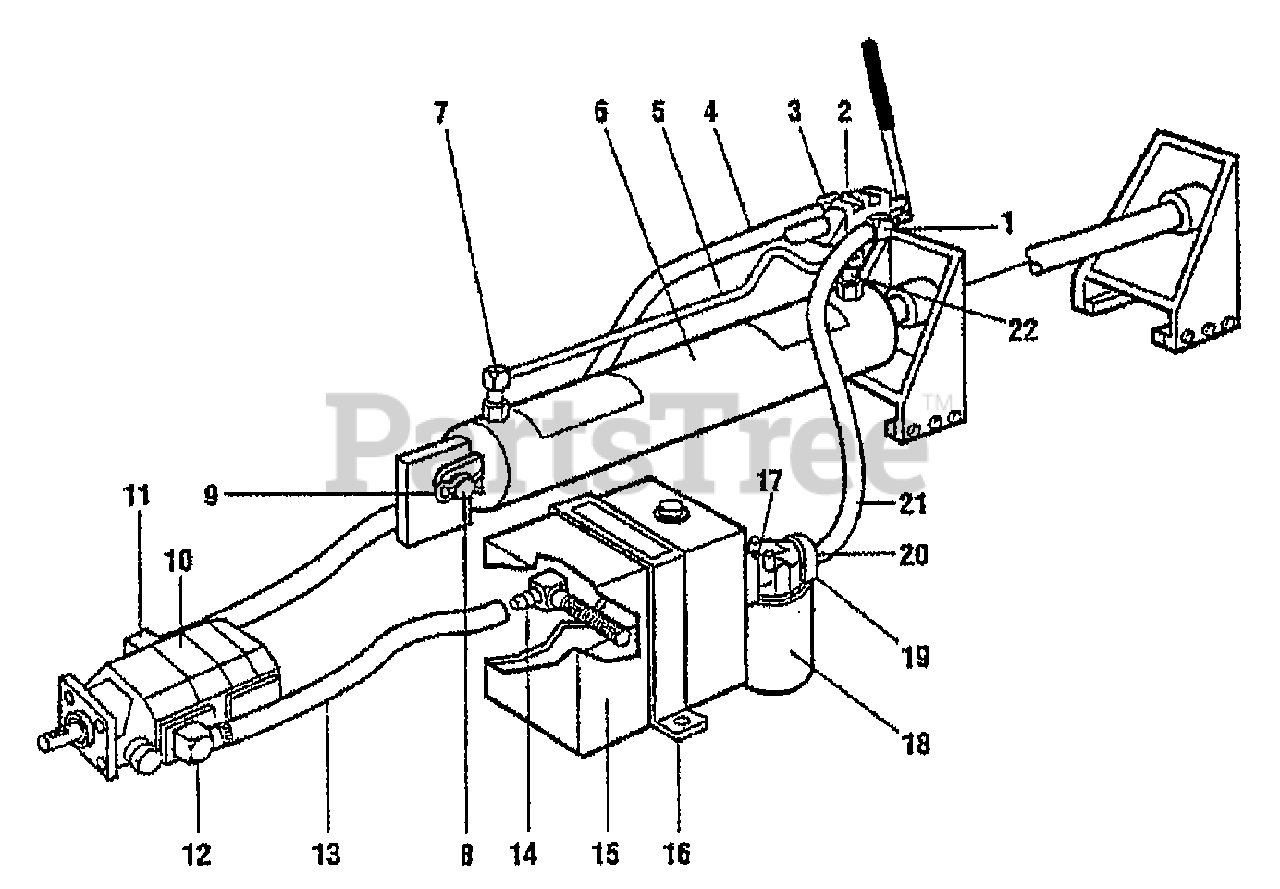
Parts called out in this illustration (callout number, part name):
1	FITTING-90 DEG. 4501-12MP-12HI
2	VALVE-ENERGY
3	FITTING-90 DEG. 2501-10MJ-12MP
4	HOSE-HP 8C2AT-8MP-10FJX-45"
5	TUBING-FORMED 21-1/16"LONG
6	CYLINDER-3 1/2" TMC
7	FITTING-90 DEG. 2501-08MJ-08MP
8	PIN-CLEVIS F/CYL
9	CLIP-CLEVIS PIN F/CYL
10	PUMP-2 STAGE BARNES 11 GPM
11	FITTING-90 DEG. 5502-08MP-08FP
12	FITTING-90 DEG.4404-12HI-08MP
13	HOSE-LP 3/4" ID X 24"
14	STRAINER & FTG F/PLASTIC TANK
15	TANK-PLASTIC
16	STRAP-TANK 14 GAX1"X24-1/4"
17	NIPPLE-BLK PIPE 3/4"X2"
18	ELEMENT-FILTER
19	HOUSING-FILTER
20	FITTING-90 DEG. 4244-12HB-12MP
21	HOSE-LP 3/4" ID X 17"
22	STRAIGHT MALE CONNECTOR
